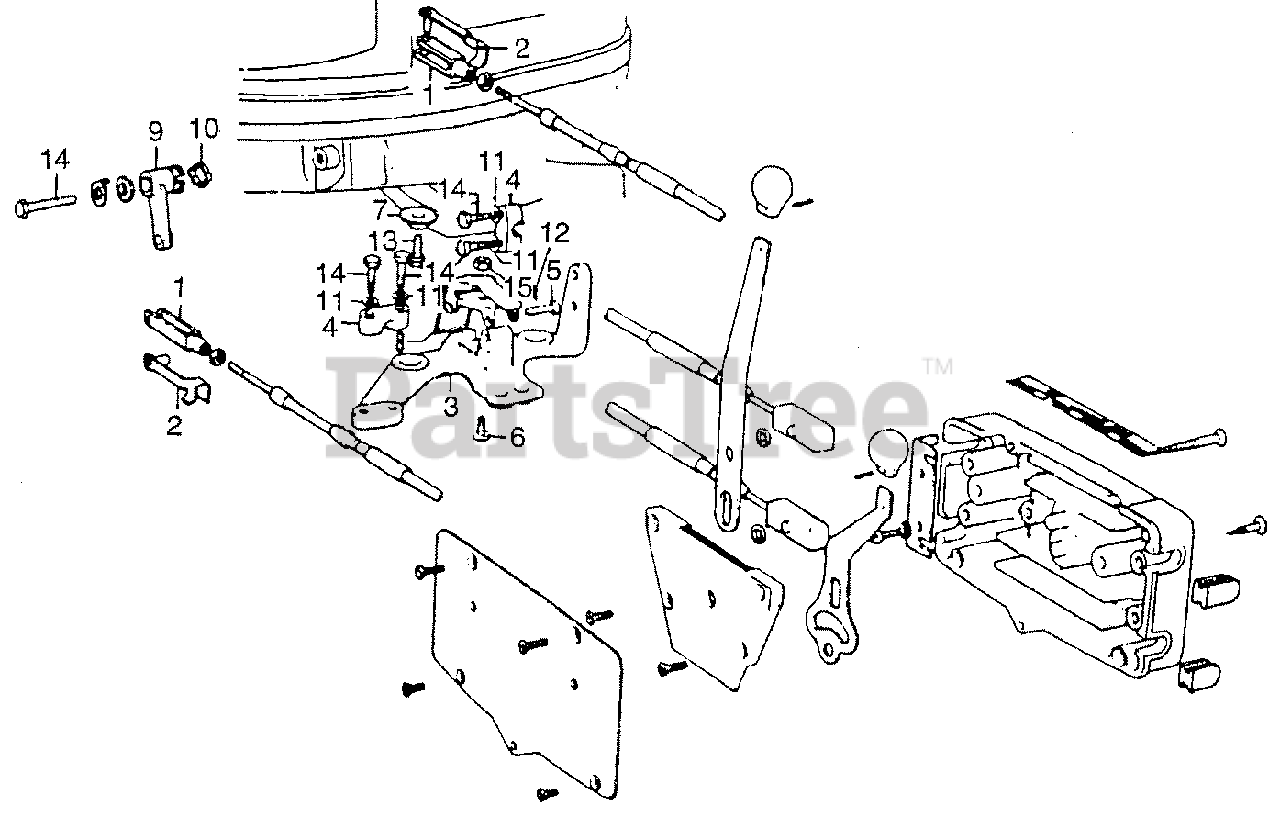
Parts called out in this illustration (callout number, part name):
1	CLEVIS, CABLE (NOT AVAILABLE)
2	PIN, CABLE (NOT AVAILABLE)
3	BRACKET, STEERING *PB1* (DARK BLUE)
4	HOLDER, CABLE *PB1* (DARK BLUE) (NOT AVAILABLE)
5	PIN, CLAMP
6	SCREW, ADJUST (NOT AVAILABLE)
7	GUIDE, BRACKET (NOT AVAILABLE)
9	LEVER, SHIFT
10	CLIP, PIN RETAINER
11	WASHER, SPRING (6MM)
12	PIN, COTTER (1.6MM)
13	BOLT, HEX. (6X20)
14	BOLT, HEX. (6X28)
15	NUT, HEX. (6MM)
NI	BOLT, HEX. (6X14)
